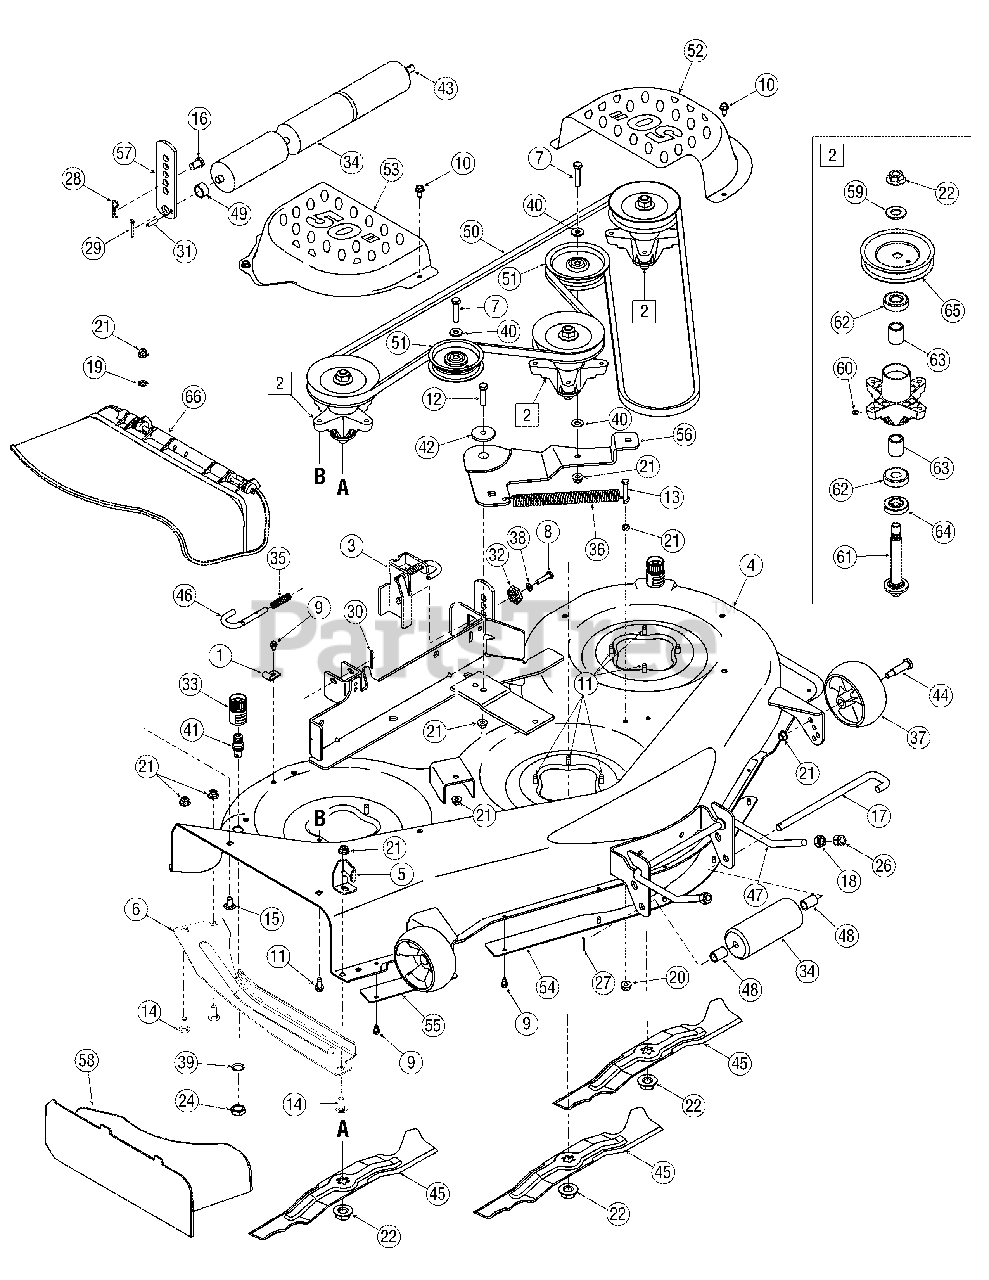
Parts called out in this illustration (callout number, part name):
1	Bracket, Hook Retainer
2	Spindle Assembly
7	Screw, Hex Cap, 3/8-16 x 1.75 Gr5
8	Screw, Hex Cap, 5/16-18 x 1.25 Gr5
9	Screw, Hex Wash. Hd. Tapp, 1/4-20 x .5
10	Screw, Hex Wash. Hd. Tapp, 5/16-18 x .5
11	Screw, Hex Wash. Hd. Tapp, 5/16-18 x .75
12	Screw, Hex Cap, 3/8-16 x 1.25 Gr5
13	Screw, Hex Cap, 5/16-18 x 2.0 Gr5
14	Screw, Carriage, 3/8-16 x 1.0
15	Screw, Carriage, 3/8-16 x .75
16	Pin, Clevis, .5 x .78
17	Pin, Roller, .5 x 10.06
18	Nut, Hex, 1/2-13 Gr5
19	Nut, Push, 3/8
20	Nut, Hex Flange Insert Lock, 5/16-18 GrF
21	Nut, Hex Flange Insert Lock, 3/8-16 GrF
22	Nut, Hex Flange, 5/8-18
24	Nut, Hex, M16-1.5
25	Nut, Hex, 5/16-18 Gr5
26	Nut, Hex Insert Lock, 1/2013
27	Pin, Cotter, 3/32 x 1.0
28	Pin, Click, .092 x 1.64
29	Pin, Cotter, 5/32 x 1.25
30	Pin, Cotter, 1/8-1.25
31	Pin, Spring, 1/4 x 1.0
32	Gear, Deck Adjust
33	Adapter, Water Nozzle
34	Roller, Front
35	Spring, Compression, .531 x 1.75
36	Spring, Extension, .94 x 6.74
37	Wheel, Deck Ball, 5.0
38	Washer, Lock, 5/16
39	Washer, Internal Tooth Lock, 5/8
40	Washer, Flat, .406 x .875 x .059
41	Nozzle, Deck Wash
42	Spacer, Shoulder, .884 x .190
43	Shaft, .5 x 20.8
44	Bolt, Shoulder, .496 x 2.5:3/8-16
45	Blade, 2 in 1 Star, 17.9
46	Rod, Deck Release
47	Rod, Deck Front Hanger
48	Spacer, .55 x .75 x 1.125
49	Spacer, .542 x .75 x .5
50	V-Belt, B Sec., 134 in.
51	Pulley, Idler, 4.25 Dia.
58	Plug, Mulch
59	Washer, Flat, .76 x 1.5 x .12
60	Fitting, Lube
61	Shaft, Spindle
62	Bearing, Ball
63	Spacer, .80x 1.10 x 1.322
64	Spacer, .79 x 1.84 x .55
65	Pulley, Deck
66	Chute Assembly, Discharge
